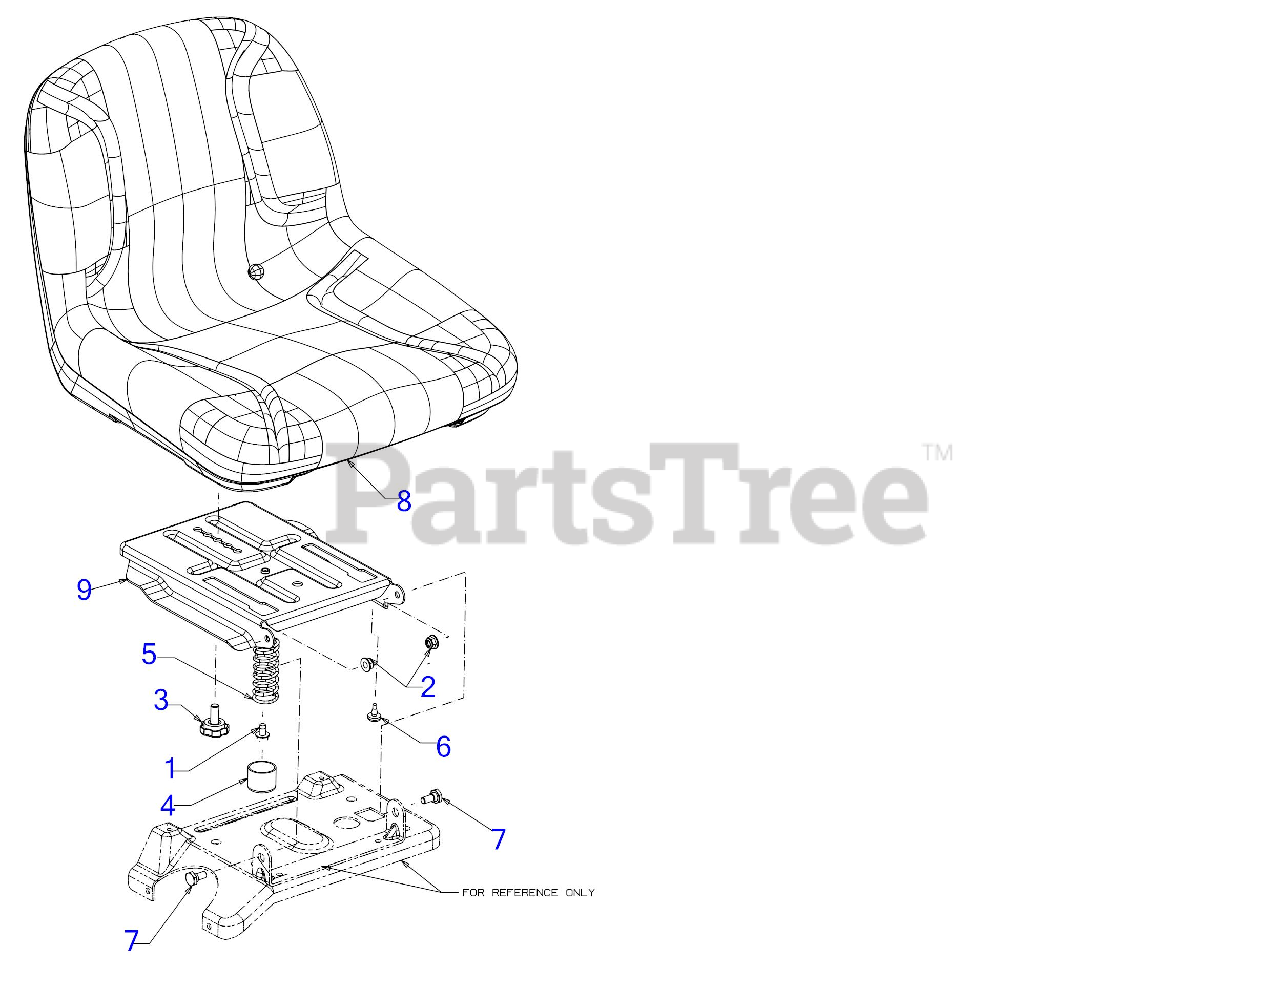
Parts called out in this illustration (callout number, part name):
1	SCREW 5/16-18 x .500
2	FLANGE LOCK NUT 5/16-18
3	SEAT ADJUSTMENT KNOB
4	SEAT SPRING CAP
5	SEAT SPRING
6	RUBBER BUMPER
7	SHOULDER SCREW .437
8	HIGH BACK SEAT (BLACK)
9	MANUAL SEAT ADJUSTMENT BRACKET
